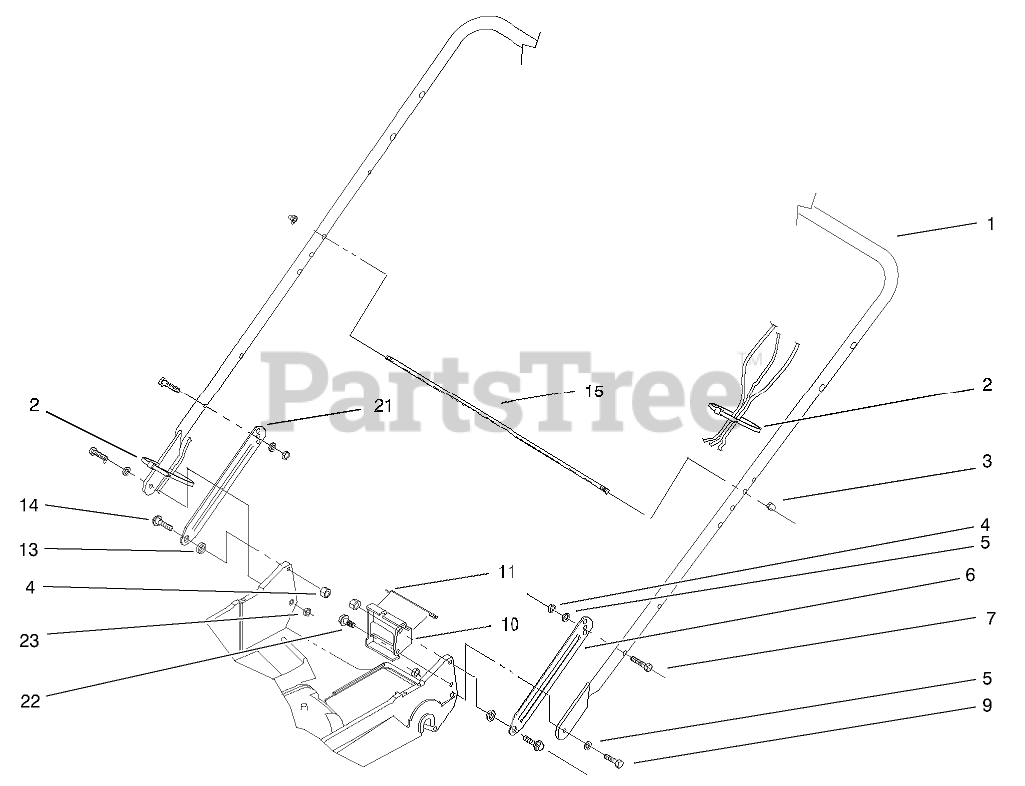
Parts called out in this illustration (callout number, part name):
2	TIE-CABLE
3	NUT-CAP
4	NUT-LOCK, NI
5	WASHER-BELLEVILLE
6	LATCH-HANDLE, LH
7	SCREW-HH
9	SCREW-HH
10	BRACKET-ADJUSTMENT, TRACTION
11	RETAINER-CABLE
13	SPACER
14	SCREW-SHOULDER
15	ROD-SUPPORT, BAG
21	LATCH-HANDLE, RH
22	SCREW-HWHTF
23	NUT-LOCK, NI
